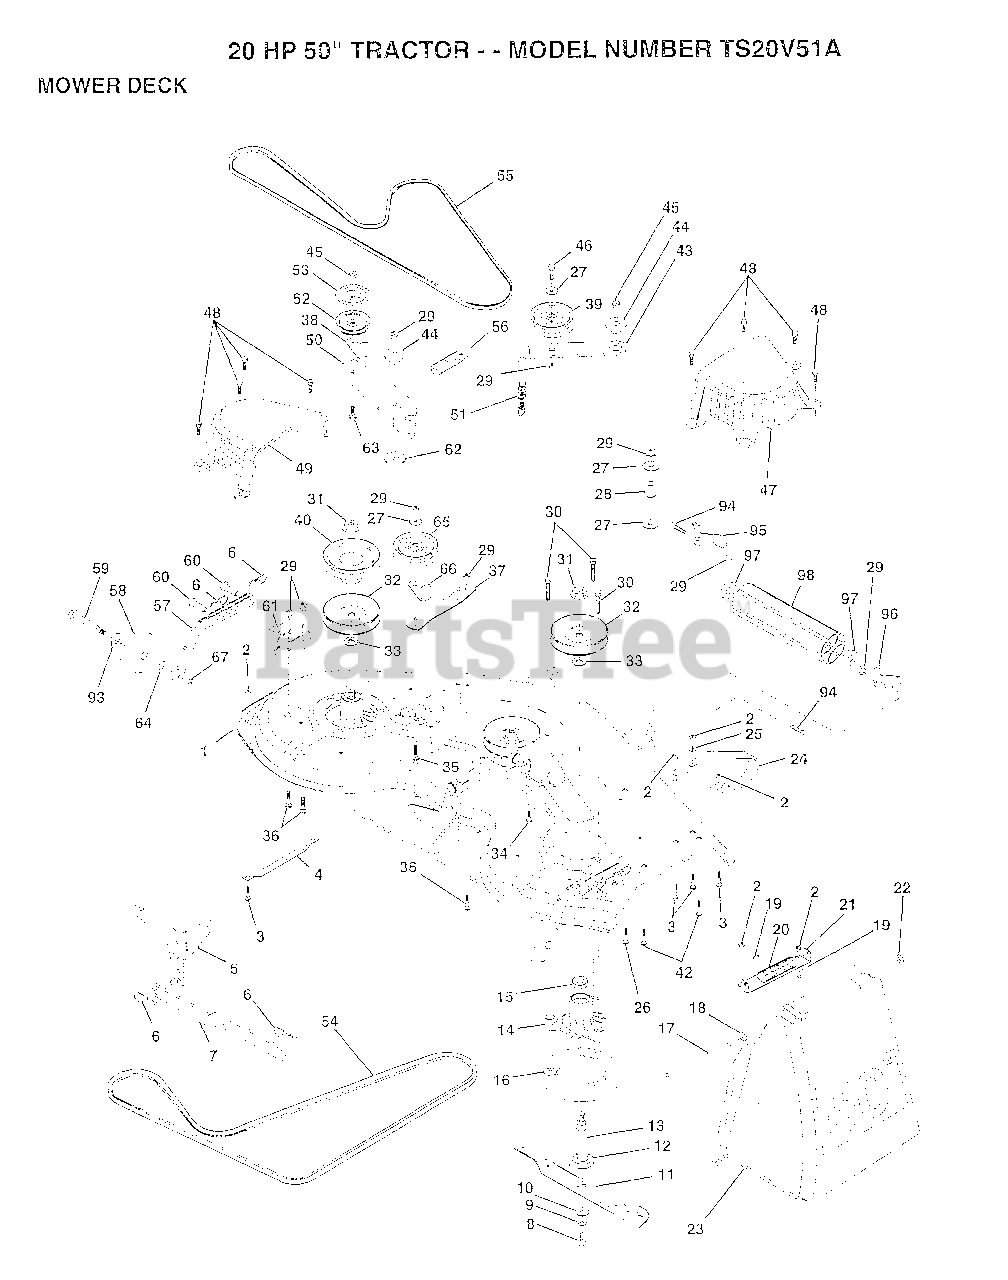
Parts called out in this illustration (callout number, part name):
1	DECK ASM MWR 50VT
2	NUT
4	RUNNER-LH M
5	BRKT.ASM.SW.44/50
8	BLADE BOLT
10	WASHER.HARD.BLADE
11	"BLADE.50"" HD"
12	BEARING.BALL
13	SHAFT.ASM.W/BRNG
14	HOUSING.MAND.44.V
15	BEARING
16	STRIPPER RND MWR
17	ROD-HINGE T
18	WASHER
19	CAP-SLEEVE LT
20	SPRING TORSION
21	BRKT DEFLECTOR
22	NUT PUSH M
23	DEFLECTOR
24	"RUNNER RH 50"" DK"
25	WASHER M
26	BOLT
27	WASHER
29	NUT
33	WASHER
34	BOLT.3/8-14X1.25
35	BOLT
36	BOLT D
37	STIFFENER.ARM.IDL
39	FLAT IDLER PULLEY
40	"PULLEY.DRIVEN.44"""
42	BOLT
43	"ARM.IDLER.SEC.44"""
44	SPACER RETAINER
47	"COVER.MAND.RH.44"""
48	SCREW.1/4-20X5/8
49	COVER.MANDREL.LH
50	ARM.IDLER.PRIMARY
51	"SPRING.SEC.44""VEN"
52	PULLEY.IDLER.VGRO
53	SHIELD.IDLER.44.V
54	BELT V PRIM 50
55	BELT.V.GDRIVE.95
56	SPRING.EXT.DECK.
57	BAR.ASM.GUAGE.WHL
58	WHEEL.GAGE.BLK.PL
59	BOLT M
60	PIN.CLEVIS
61	BRACKET.GUAGE.WHL
62	HARDENED WASHER
63	BOLT.3/8-16X1.50
64	WASHER
65	IDLER-FLAT T
67	LOCKNUT
93	WASHER
97	WASHER
99	BOLT
